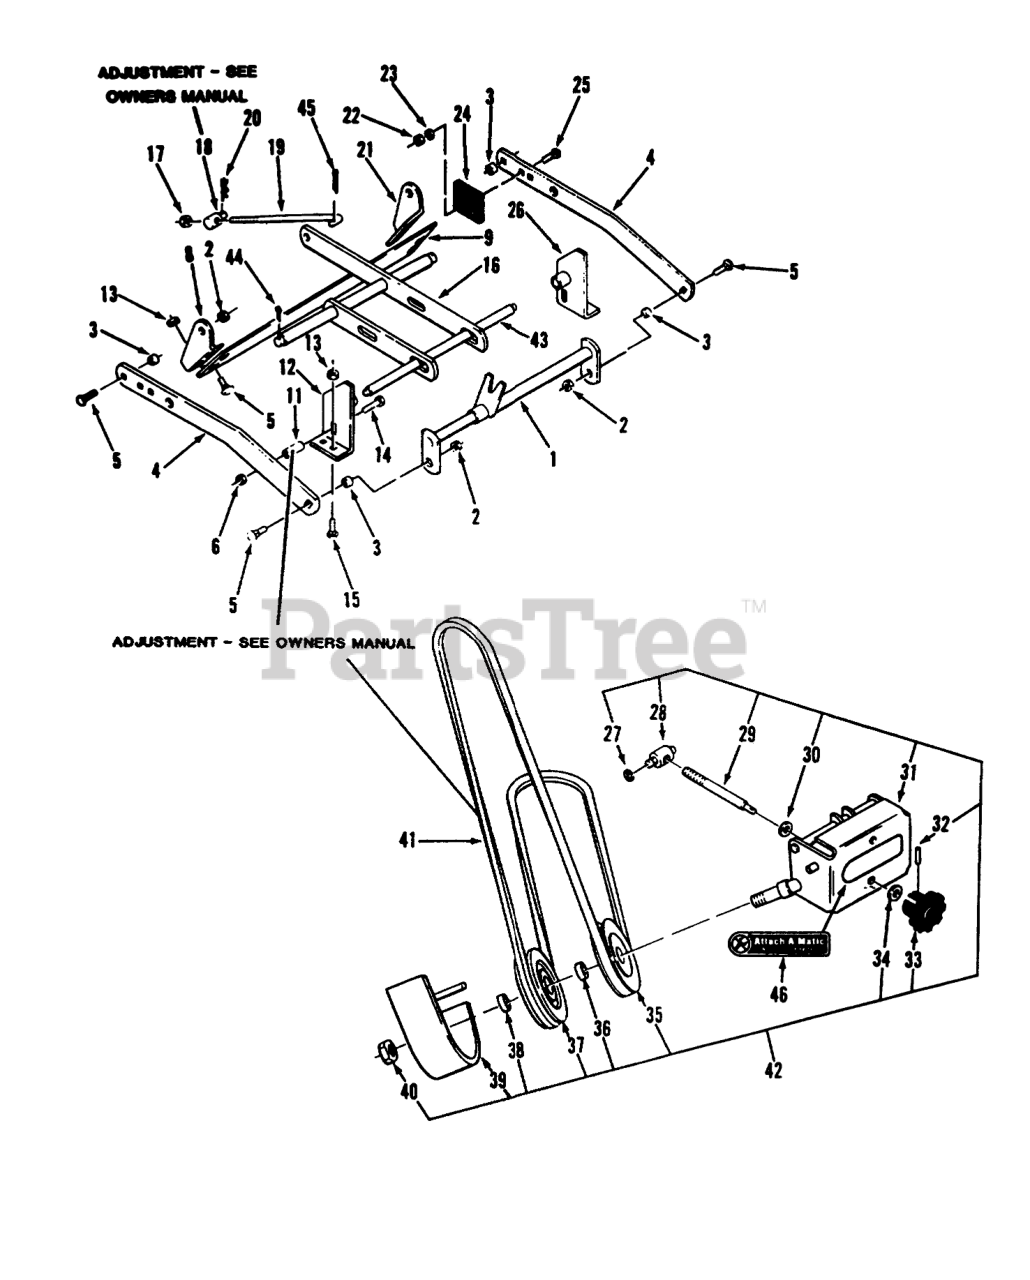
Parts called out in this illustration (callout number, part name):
1	Hitch
2	LOCKNUT-FLANGE
3	SPACER
4	Bar Draft
5	BOLT-CARR
6	Nut
8	Bracket-R.H.
12	Bracket-R.H.
13	NUT-LOCK, NI
14	BOLT-CARR
15	BOLT-CARR
16	Leveler
17	NUT-LOCK, NI
18	TRUNNION-LIFT
19	Rod-Lift
20	Hairpin
21	Bracket-L.H.
21	Bracket-L.H. Rear
22	NUT-LOCK, NI
23	WASHER-FLAT
24	BUMPER
25	SCREW-CARR
26	Bracket-L.H.
27	RING-RETAINING
28	TRUNNION-DOUBLE
29	ROD ADJ
30	WASHER-FLAT
31	Front Support
32	PIN-ROLL
33	KNOB-ADJUSTMENT
34	WASHER-SPRING
35	Pulley-V
36	SPACER
37	PULLEY-FLAT IDLER
38	SPACER-OUTER
39	Belt Cover
40	Nut
41	V-BELT
42	Front Idler Assembly (Incl. Ref. #27-40 & 46)
43	Front Shaft
44	PIN-COTTER
45	PIN-COTTER
46	Decal-Attac-O-Matic
